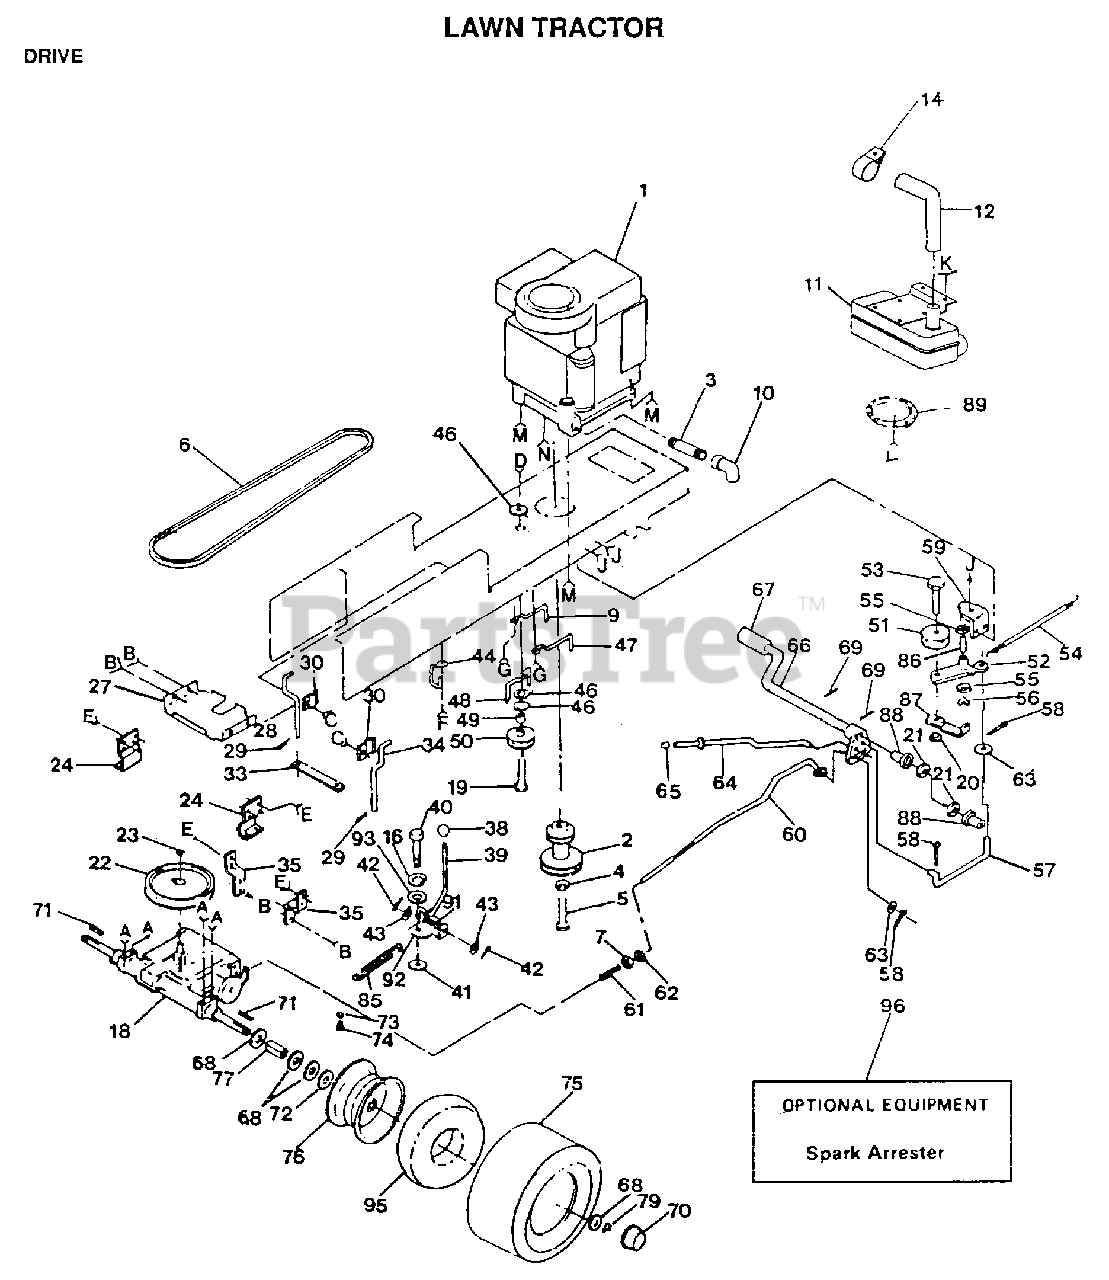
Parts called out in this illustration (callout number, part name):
3	PIPE NIPPLE
4	LOCKWASHER
5	BOLT
6	BELT-V.90.0.GD.DR
7	NUT
9	KEEPER BELT ENGLH
10	ELBOW
12	TUBE, EXHAUST
14	"CLAMP,MUFFLER"
16	LOCKWASHER
19	BOLT
21	WASHER LT
22	PULLEY TRANS
24	BRACKET LT
27	BRKT SUPPORT LT
28	KEEPER BELT LH
29	SPRING.RETAINER
30	CLAMP LT
33	STRAP LOCATOR
34	KEEPER BELTRH
35	STRAP TORQUE
38	CONTROL KNOB LT
39	ROD SHIFTER
41	WASH-SHFT PLT LT
42	PIN COTTER 1/8
43	WASHER
46	WASHER
47	"KEEPER,BLT ENG LT"
48	BELT KEEPER LT
49	SPACER T
50	PULLEY.IDLER.FLAT
52	ARM IDLER
54	"SPRING, RETURN LT"
55	WASHER LT
56	KLIP RING
57	"LINK, CLUTCH T"
58	COTTER PIN
59	BRKT ASM
60	BRAKE ROD LT
61	SPRING ROD LT
62	NUT
63	WASHER
67	PEDAL COVER T
68	WASHER
70	HUB CAP
71	SQUARE KEY
72	WASHER
73	VALVE CAP
74	VALVE STEM LT
77	SPACER LT
79	E-RING LT
86	"LY, BEARING"
87	RETAIN BELT
88	NYLON BEARING
89	DEFLECTOR.222573
91	SPRING LT
92	PLATE SHIFT LT
93	WASHER LT
95	TUBE.18X9.5-8
96	SPARK ARREST KIT
